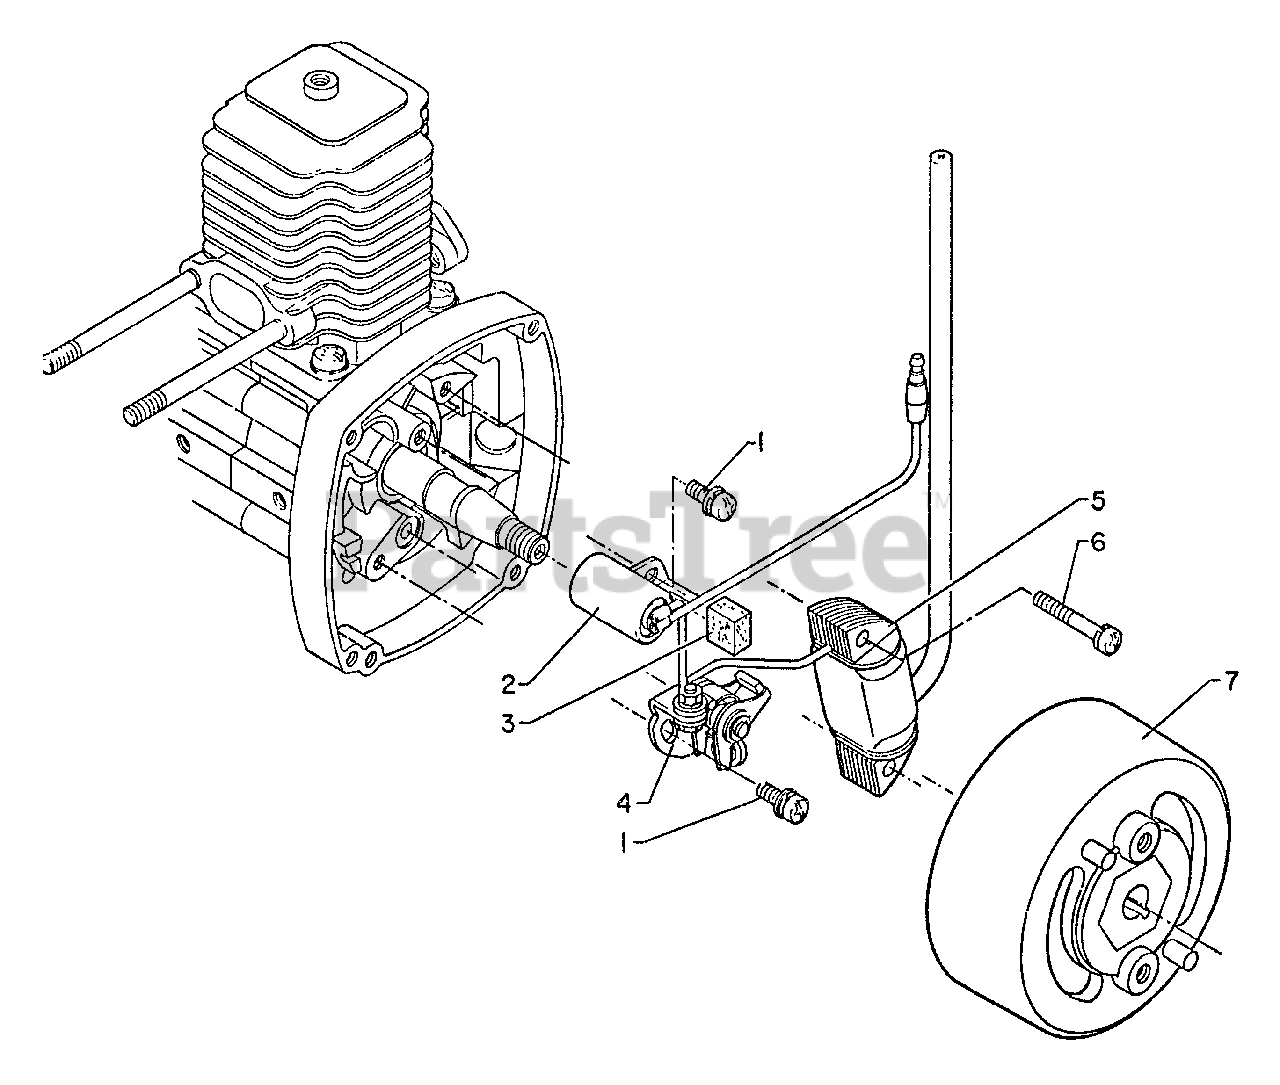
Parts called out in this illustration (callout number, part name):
1	SCREW 4×10
2	CONDENSER
3	PAD, OIL
4	CONTACT POINT SET
5	COIL, IGNITION
6	SCREW 4×25
7	FLYWHEEL
